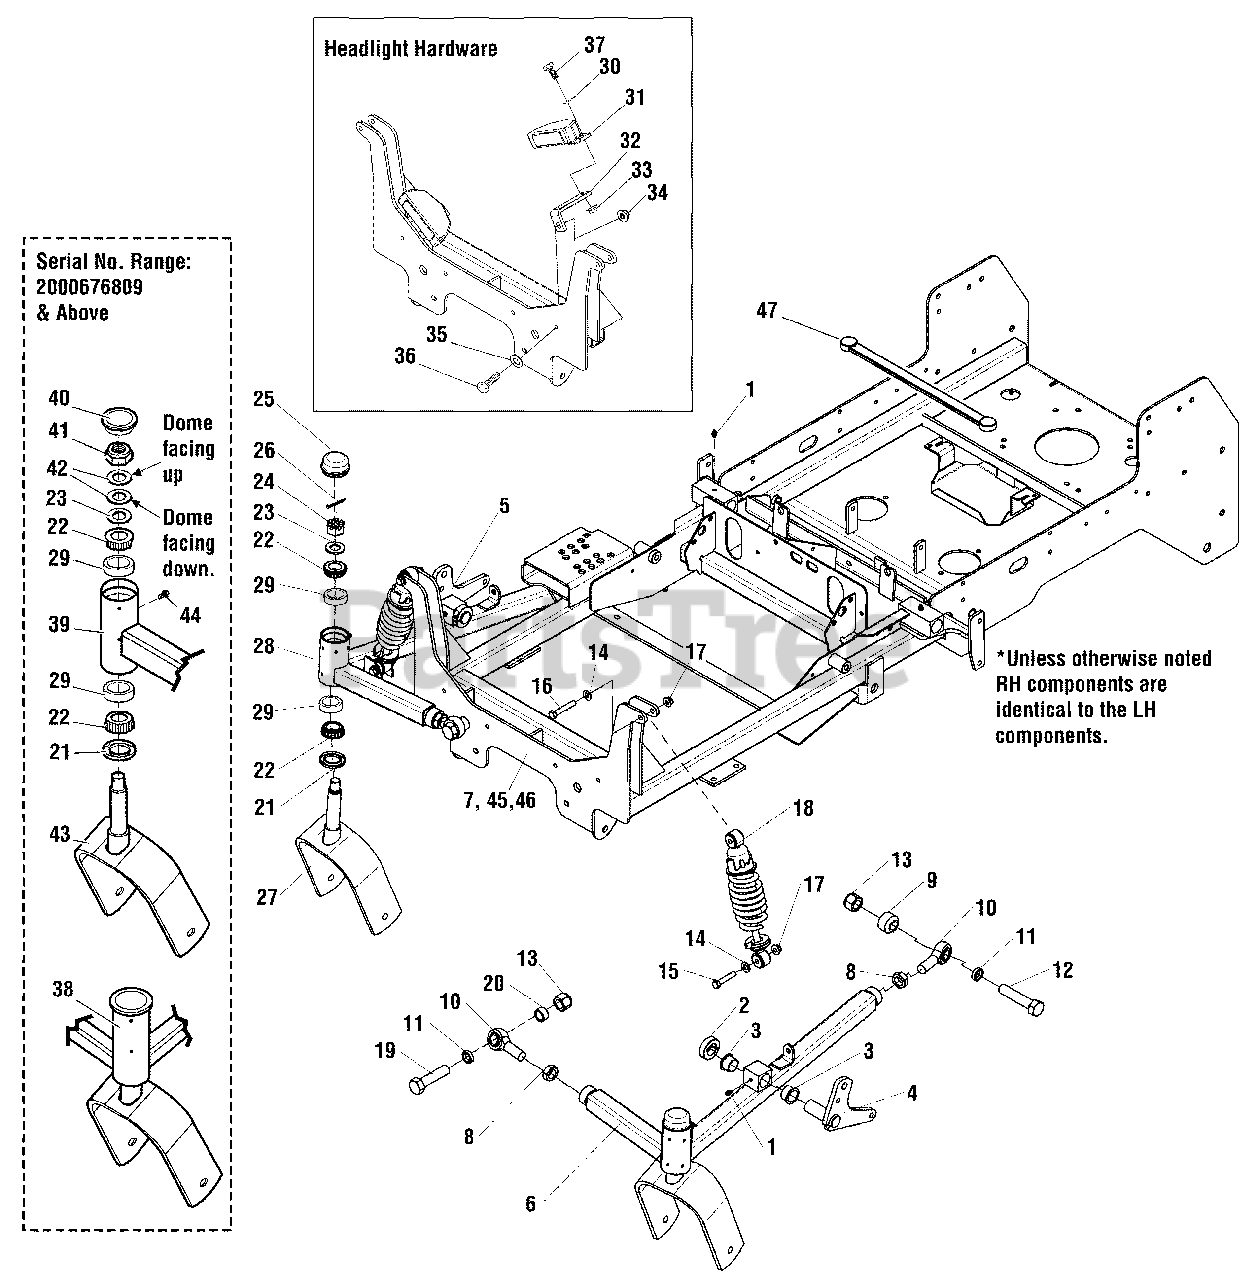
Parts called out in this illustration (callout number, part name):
1	GREASE FITTING, 1/4-28 STR
2	COLLAR, 1" SPLIT
3	BUSHING, 1.00 X 1.13 X .75, PLASTIC
4	WELD, DECK LIFT LEVER, LH - ORANGE
5	WELD, DECK LIFT LEVER, RH - ORANGE
6	WELD, FRONT A-ARM, LH - ORANGE
7	WELD, MAIN FRAME - ORANGE
8	NUT, HEX JAM, 3/4-16
9	SPACER, .75 X 1.50 X 1.00
10	BALL JOINT, 3/4-16 MALE
11	SPACER, .76 X 1.00 X .25
12	3/4-16 X 3.5" HHCS YZP GR 5
13	NUT, 3/4-16 HEX NYLON LOCK
14	WASHER 3/8" SAE
15	BOLT, 3/8-16 X 2" GD5
16	BOLT, 3/8-16 X 2-1/4" GD5
17	NUT, 3/8-16 HEX NYLOCK FLANGE
18	COIL - OVER SHOCK ASSEMBLY
19	BOLT, 3/4-16 X 3" GD 5
20	SPACER, .76 X 1.00 X .50
21	SEAL, GREASE
22	BEARING, TAPPERD ROLLER, 1"
23	WASHER, 3/4" SAE
24	NUT, 3/4-16 HEX SLOTTED
26	PIN, COTTER, 1/8" X 1-1/4"
27	WELD, CASTER YOKE - ORANGE
28	WELD, FRONT A-ARM, RH - ORANGE
29	BEARING CUP
30	WASHER, 1/4 SAE (5025154)
31	HEADLIGHT, 4" RECTANGULAR
32	MOUNT, HEAD LIGHT - ORANGE
33	NUT, 1/4-20 HEX NYLOCK FLANGE (5025391)
34	NUT, 5/16-18" NYLOCK FLANGE
35	WASHER, 5/16" SAE FLAT
36	BOLT, 5/16-18 X 1"
37	BOLT, 1/4-20 X 1", GD
38	WELD, FRONT A-ARM - LH - ORG
39	WELD. FRONT A-ARM - RH - ORG
40	CAP, LOW PROFILE, STEEL
41	NUT, 3/4-16 HEX JAM NYLON LOCK
42	BELLEVILLE WASHER, 1.500 X .755
43	WELD, CASTER YOKE - ORG
44	BOLT, 1/4-28 X 1/2, GD5 YZ
45	WELD, MAIN FRAME
46	WELD, MAIN FRAME, IS2000/COBALT - ORG
47	STRAP-BLACK RUBB
